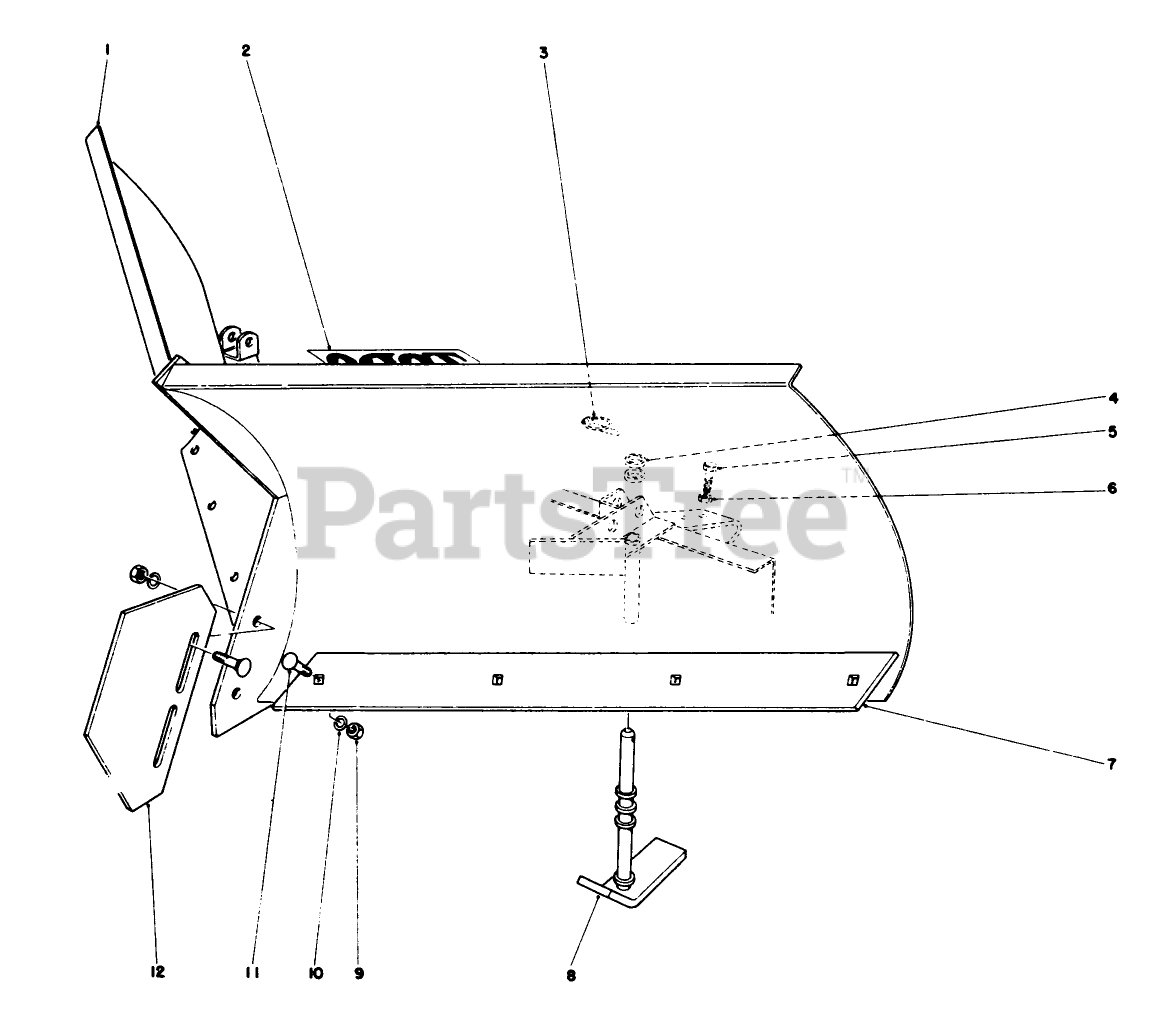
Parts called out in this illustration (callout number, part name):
1	V-Plow
2	Decal
3	PIN-LYNCH
4	SPACER TUBE B
5	SCREW-HH
6	NUT-JAM
7	Blade-Scraper
8	Skid
9	NUT-HH
10	WASHER-LOCK
11	SCREW-CARR
12	Nose Skid
